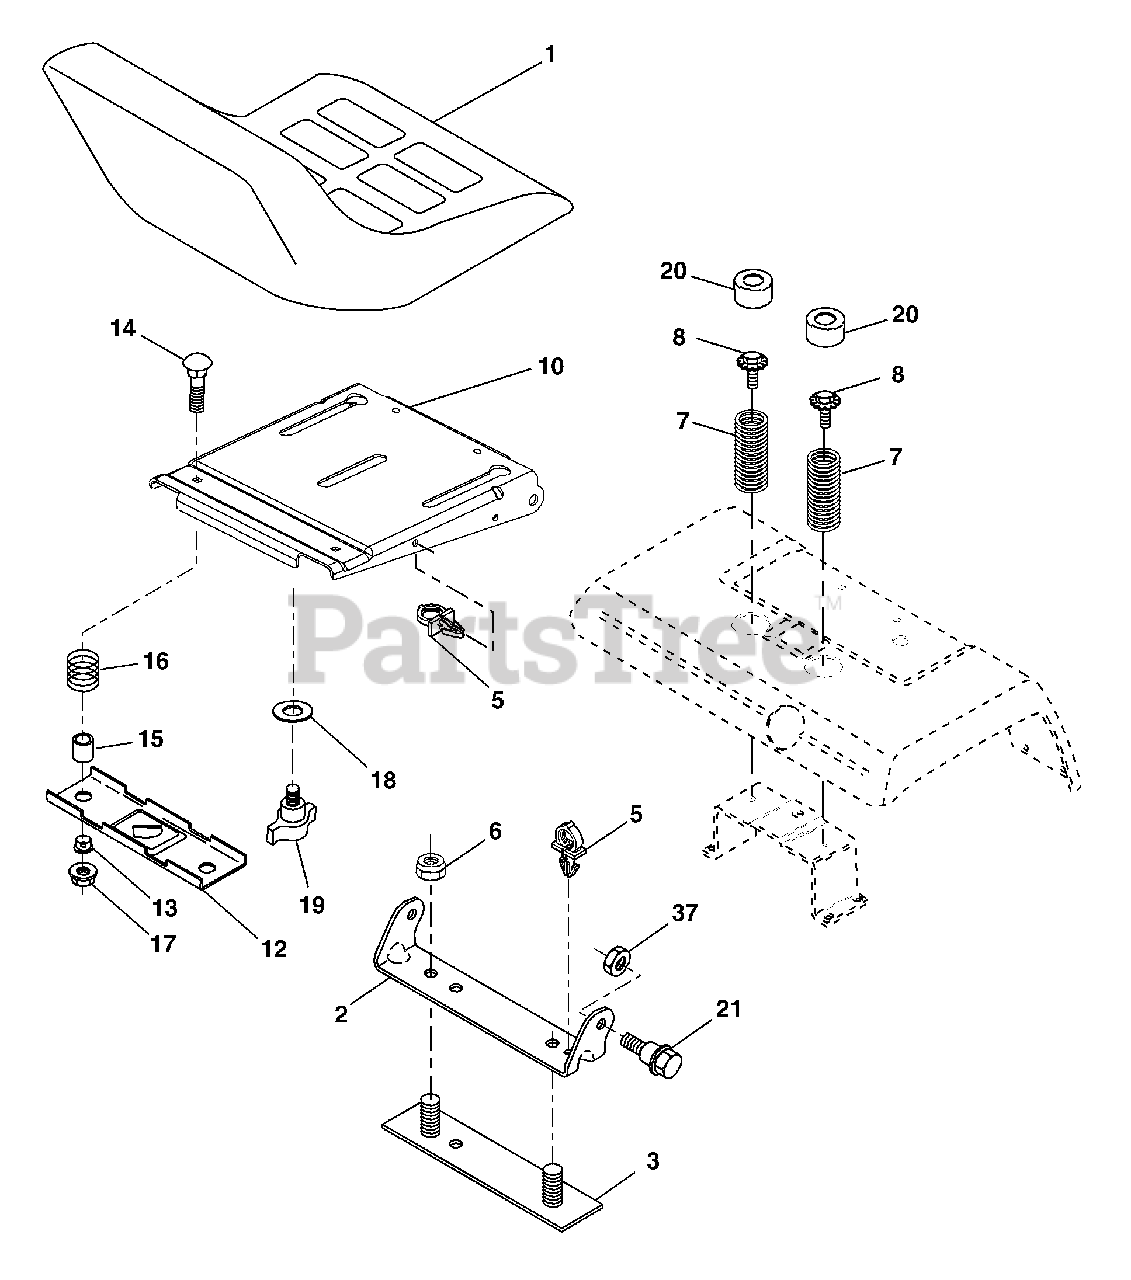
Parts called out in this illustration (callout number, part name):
1	Seat
2	Bracket, Pivot Seat
3	Strap Asm.
5	Clip, Push-In Hinged
6	Nut, Crownlock 3/8-16
7	Spring, Seat Cprsn.
8	Bolt 5/16-18 unc x 3/4 w/Sems
10	Pan, Seat
12	Bracket, Mounting Switch
13	Bushing, Snap
14	Bolt, Carriage 1/4-20 x 1-1/2
15	Spacer, Split
16	Spring, Cprsn.
17	Nut, Lock 1/4 Lg. Flg. Gr. 5
18	Washer 17/32 x 1-3/16 x 12 Ga.
19	Knob, Seat
20	Cap, Spring Seat Blk
21	Bolt 5/16-18 unc-2A
37	Nut, Crownlock 5/16-18
